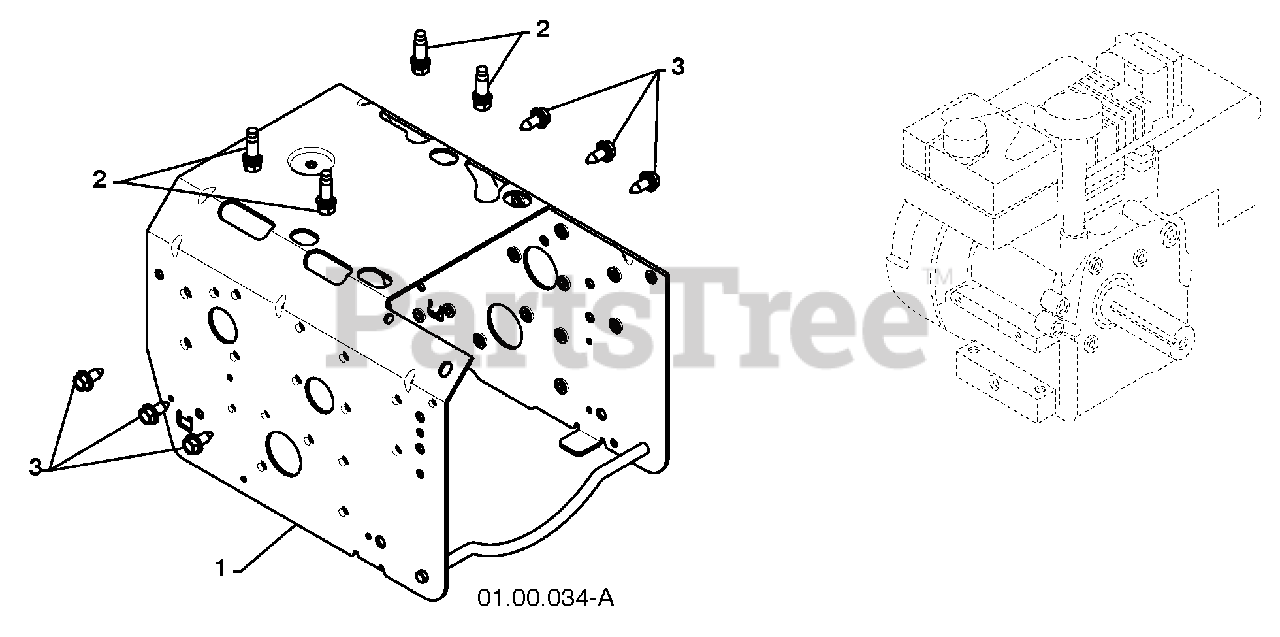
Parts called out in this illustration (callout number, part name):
1	Frame Assembly
2	Bolt 3/8-16
3	Screw 5/16-18 X .750
